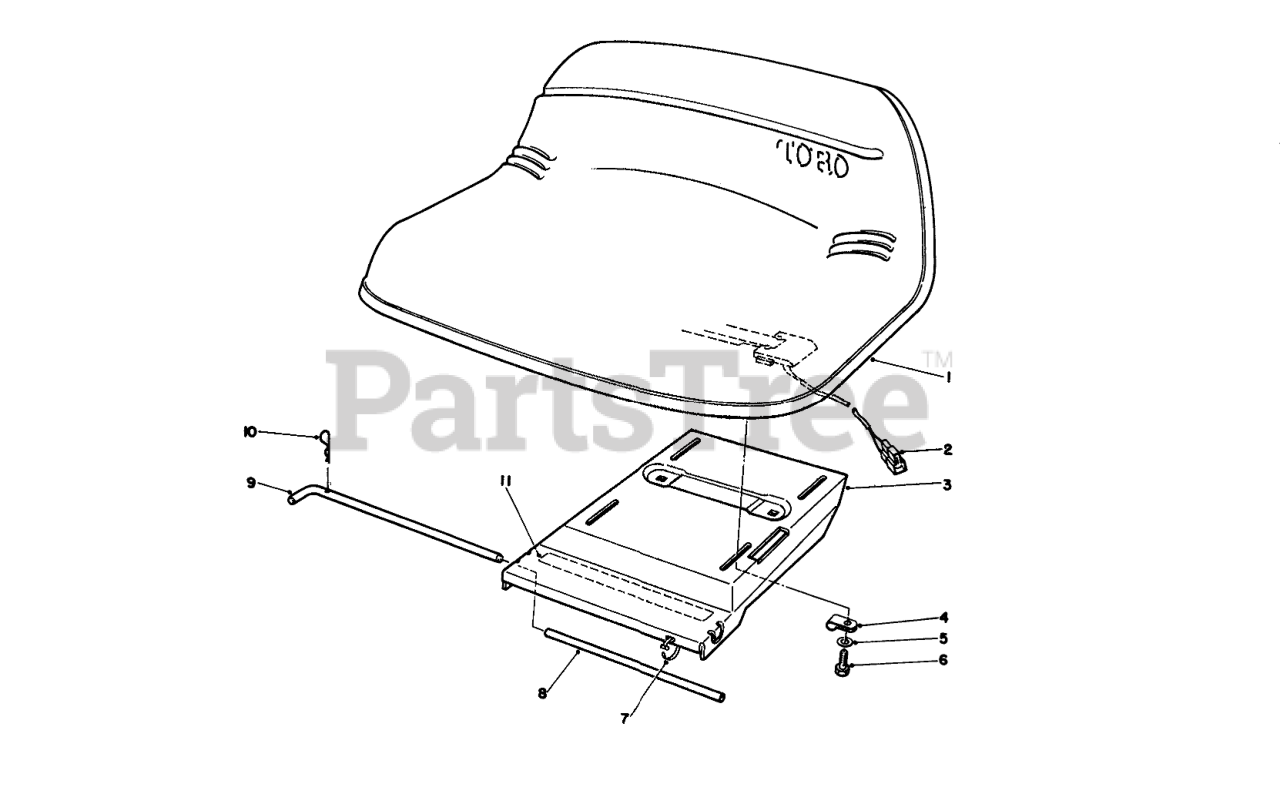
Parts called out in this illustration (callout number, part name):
1	Seat
2	SWITCH-SEAT
3	Base-Seat
4	CLAMP
5	WASHER-PLAIN
6	SCREW-HH
7	TIE-CABLE
8	TUBE-SEAT
9	ROD-SEAT BASE
10	PIN-COTTER
11	DECAL
